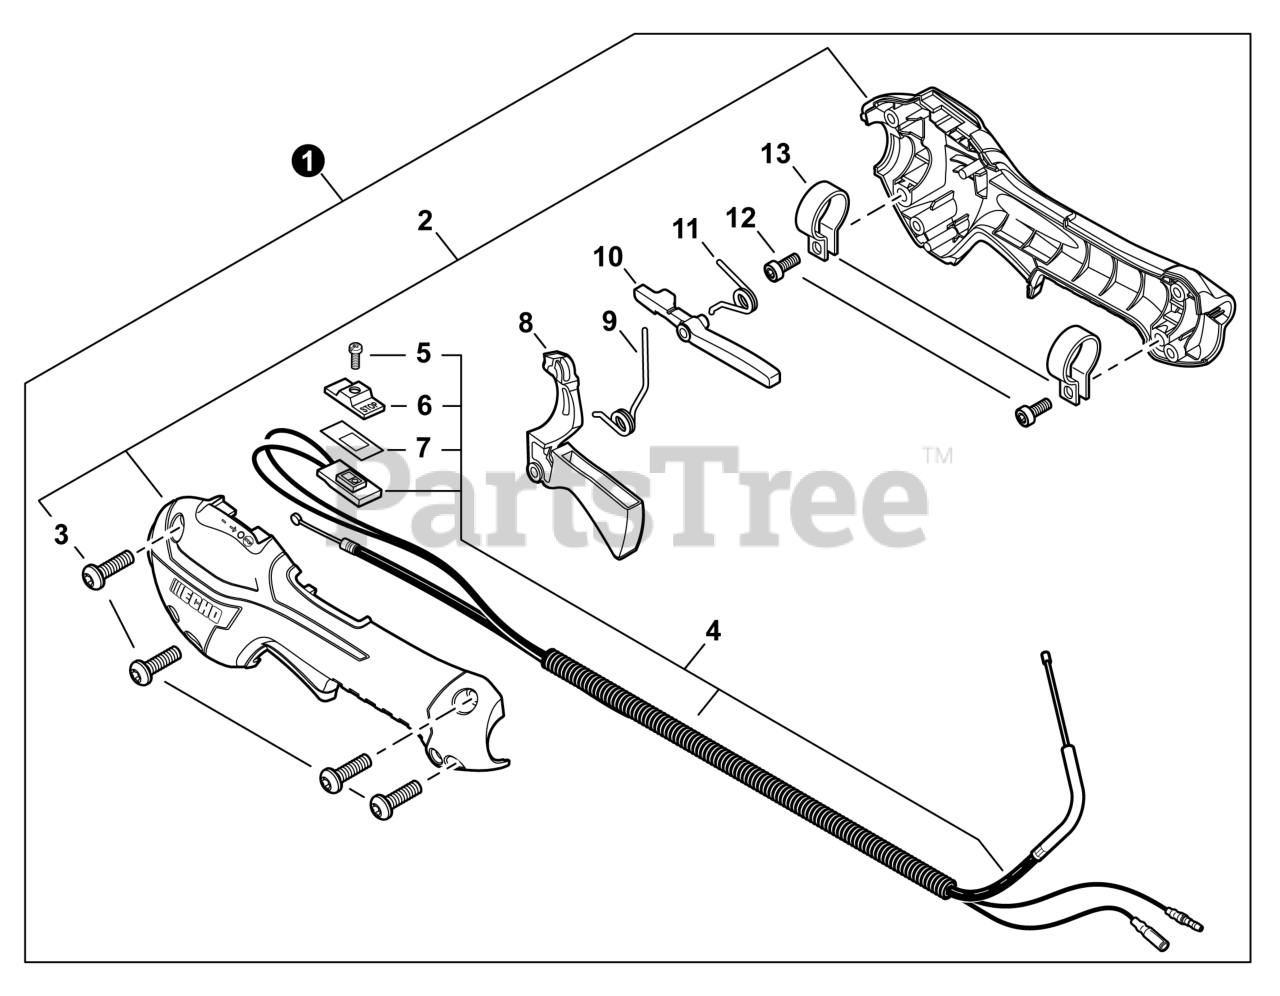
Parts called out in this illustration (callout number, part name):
1	CONTROL HANDLE ASSY
2	CONTROL HANDLE KIT
3	BOLT, TORX 5×16
4	CABLE ASSY, CONTROL
5	SCREW 3×10
6	KNOB, SWITCH - ORANGE
7	SEAL, SWITCH
8	TRIGGER, THROTTLE
9	SPRING, TORSION
10	LEVER, THROTTLE LOCKOUT
11	SPRING, TORSION
12	BOLT, TORX 5×16
